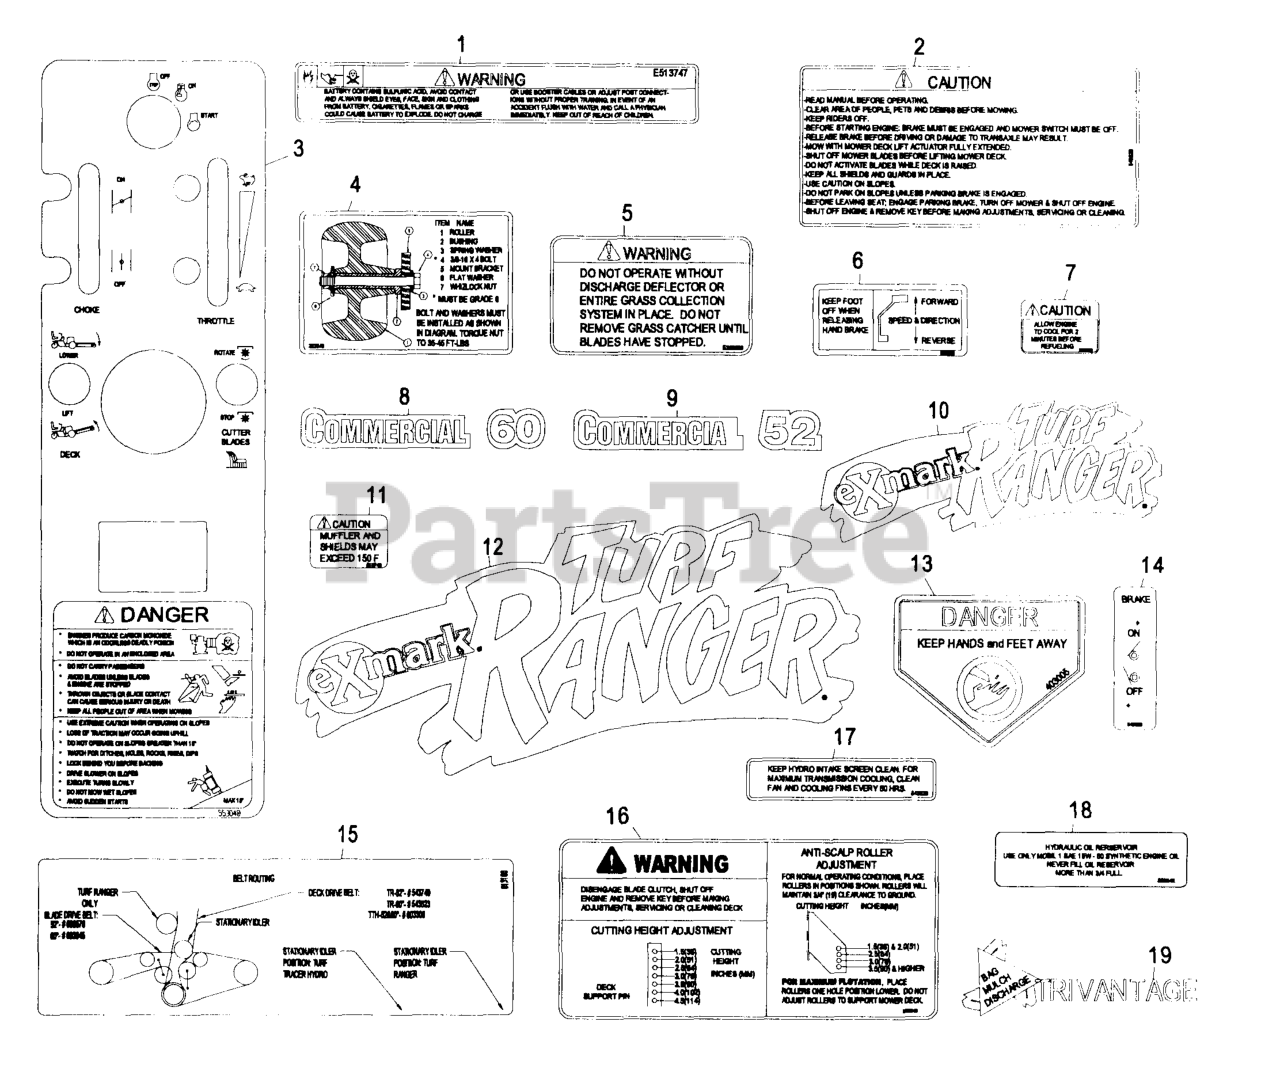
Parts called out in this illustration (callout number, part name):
1	DECAL-BATTERY
4	DECAL,ROLLER MOUNTING
5	DECAL-WARNING, DISCHARGE
6	DECAL,FOOT PEDAL
8	DECAL,COMMERCIAL 60
9	DECAL,COMMERCIAL 52
12	DECAL,SWASH RANGER
13	DECAL-DANGER
15	DECAL,BELT ROUTING
16	DECAL,ANTI SCALP
17	DECAL,INTAKE
18	DECAL,HYDRAULIC TANK
